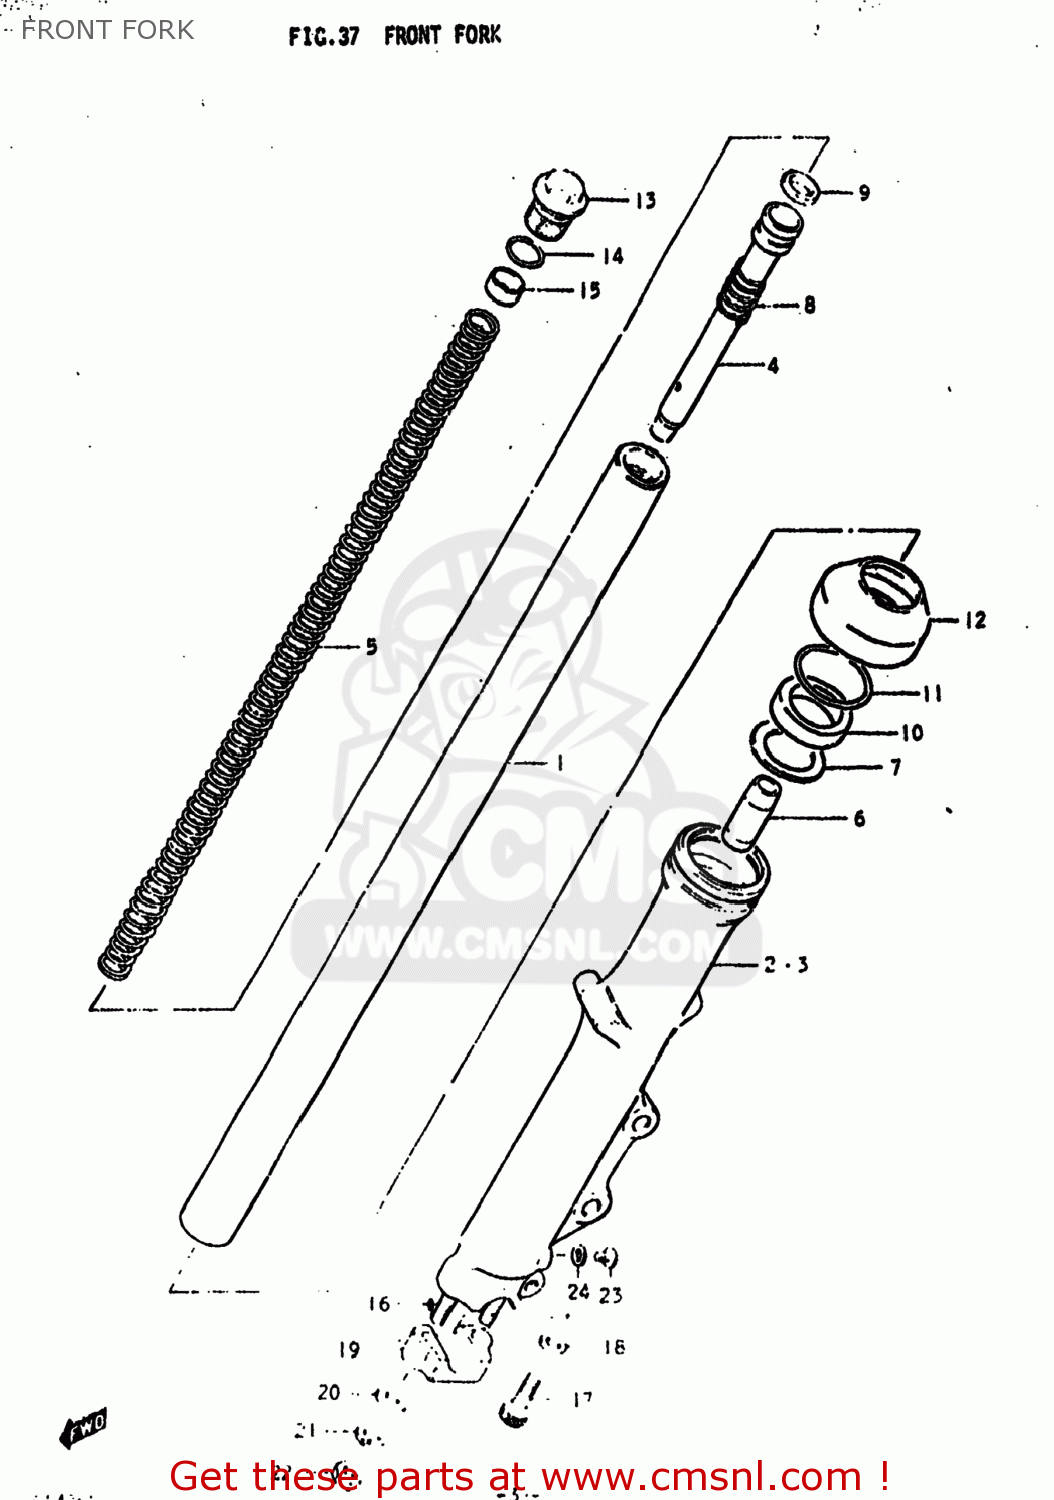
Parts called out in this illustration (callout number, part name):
0	DAMPER ASSEMBLY,LEFT
1	TUBE,INNER
2	TUBE,FORK,LEFT,OUTER
3	TUBE,FORK,OUTER,RIGHT
4	CYLINDER,FRONT FORK
5	SPRING
6	PIECE,OIL LOCK
7	SPACER,OIL SEAL
8	SPRING,REBOUND
9	RING,PISTON
10	OIL SEAL,FRONT FORK
11	CIRCLIP,FORK OIL SEAL
12	BOOT
13	BOLT
14	O RING
15	SPACER,FRONT FORK SPRING
16	STUD 8X25
17	BOLT
18	GASKET (NAS)
19	HOLDER,AXLE
20	WASHER
21	LOCK WASHER
22	NUT
23	SCREW
24	GASKET (NAS)
